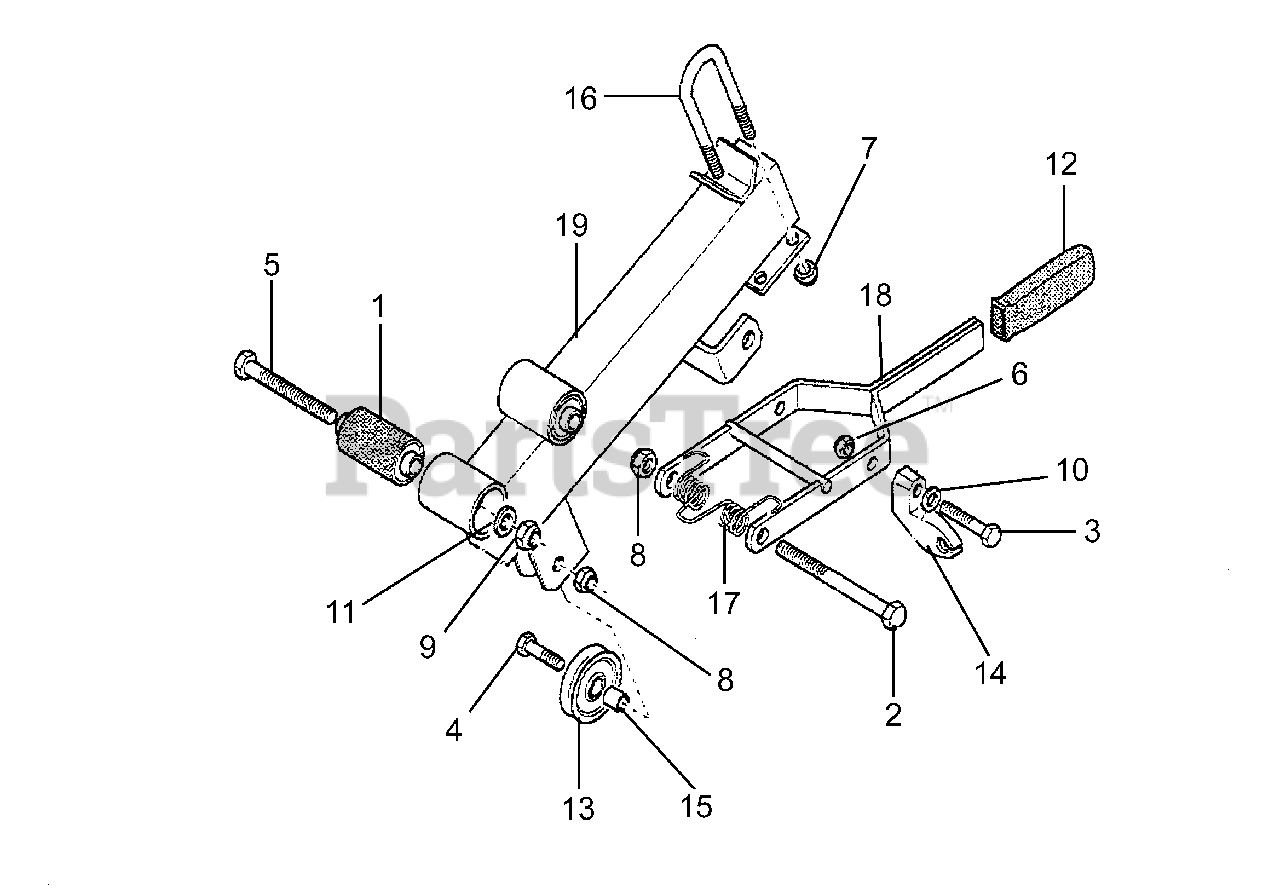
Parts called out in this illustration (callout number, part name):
1	SILENTBLOCK 12X40X58X66-47602
2	HEX SCREW M10X110 UNI 5737 8G
3	HEX SCREW M8X35 UNI 5739-8G
4	HEX. SCREW M10X30 UNI 5739-8G
5	HEX SCREW M12X95 UNI 5739 8G
6	NUT M8 UNI 5588-5S
7	LOCKNUT M 8
8	LOCKNUT M 10
9	SELF-LOCKING NUT M12 LOW
10	SPRING WASHER B 8.4 DIN 137
11	SPRING WASHER B 13 DIN 137
13	BRAKE PULLEY
14	CUT CONTROL ROD MOUNT
15	BRAKE PULLEY BUSHING
16	HANDLEBAR U BOLT
17	HANDLEBAR RELEASE SPRING
18	HANDLEBAR SELECT. LEVER COMPL.
19	2-WH.TRACT.STEER.COL.W/SIL.BLO
